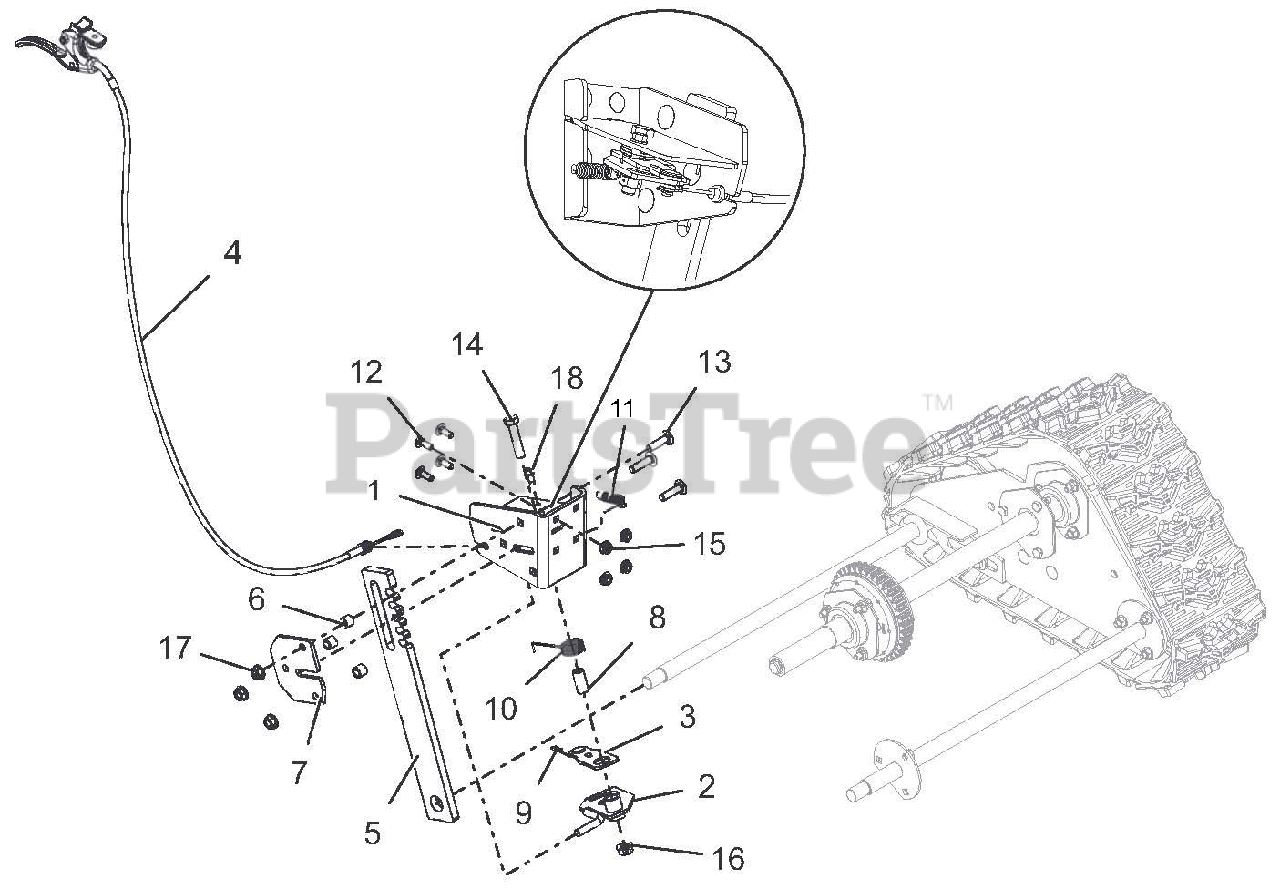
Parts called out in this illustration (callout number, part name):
1	BRACKET, HEIGHT ADJUSTER-PRO
2	LOCK, HEIGHT ADJUSTER
3	ARM, OVERTRAVEL
4	CABLE, TRACK REMOTE
5	STOP, HEIGHT ADJUSTER-PRO
6	SPACER .50 X .32 X .42
7	PLATE, HEIGHT ADJUSTER
8	BSHG-SLV .385X.500X1.045
9	PIN-HAIR INT .06X.18X.77
10	SG-TORS .067X.88
11	SPRING-EXT .047 X .438 X 1.85
12	@BLT-RDHDSQNK .25-20X.75 G5YZ
13	@BLT-RHDSHSQNK.31-18X1.25 G5YZ
14	@BLT-HEX .38-16X1.75 GR5 YWZC
15	@NUT-LK-CTR-FLG .25-20 YWZC
16	NUT-LK-CTR-FLG .38-16 YWZC
17	@NUT-LK-TOP-FLG .31-18 YWZC
18	SCR-TAP .25-20X.50 HWH TR YWZ
